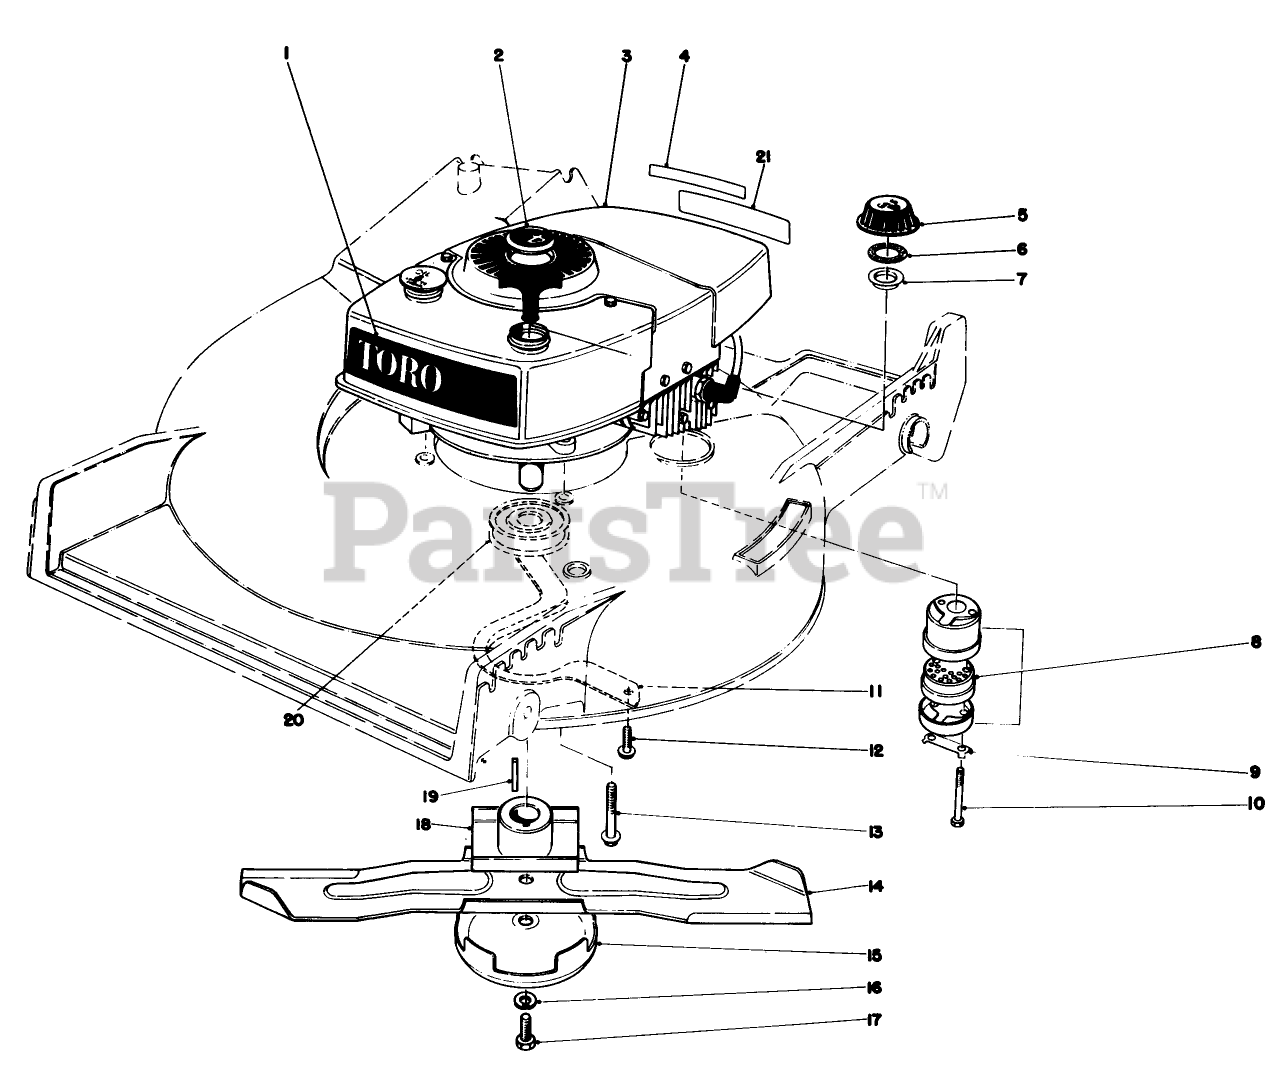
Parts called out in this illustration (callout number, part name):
3	Engine
6	GASKET
8	MUFFLER ASM
9	CLIP - LOCKING
10	SCREW-HH
16	WASHER-LOCK
17	BLADE SCREW
19	KEY-SQUARE
